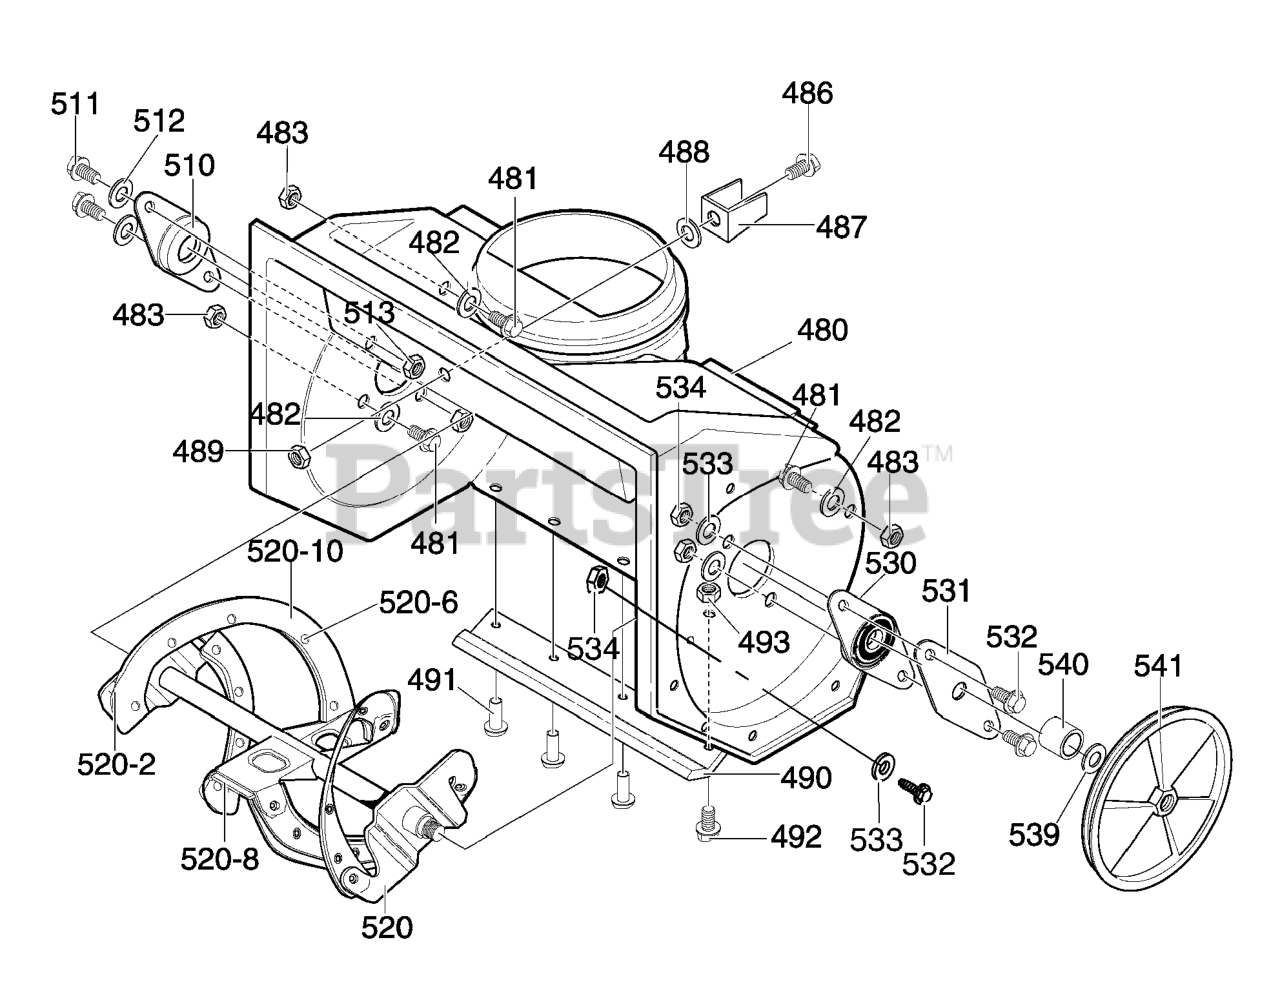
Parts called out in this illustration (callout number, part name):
480	HOUSING ASSEMBLY
481	SCREW, 1/4-20x.75
482	FLATWASHER
483	NUT, 1/4-20
486	SCREW, 1/4-20 x.63
487	BRACKET, STOP
488	FLATWASHER
489	NUT,1/4-20
490	SCRAPER BAR
491	RIVET
492	SCREW, 1/4-20x .75
493	NUT, 1/4-20
510	FLANGE BEARING
511	SCREW, 1/4-20x1.00
512	FLATWASHER
513	NUT, 1/4-20
520	AUGER ASSEMBLY
520-2	AUGER BLADE
520-6	RIVET
520-8	CENTER BLADE
520-10	AUGER & BLADE SUPPORT
530	BEARING & PLATE ASSY.
531	BEARING RETAINER
532	SCREW, 1/4-20x5/8
533	FLATWASHER,.281x.63x.065
534	NUT, 1/4-20 Reghexctrlk
539	FLATWASHER
540	SPACER, SLEEVE
541	PULLEY, POLY V
